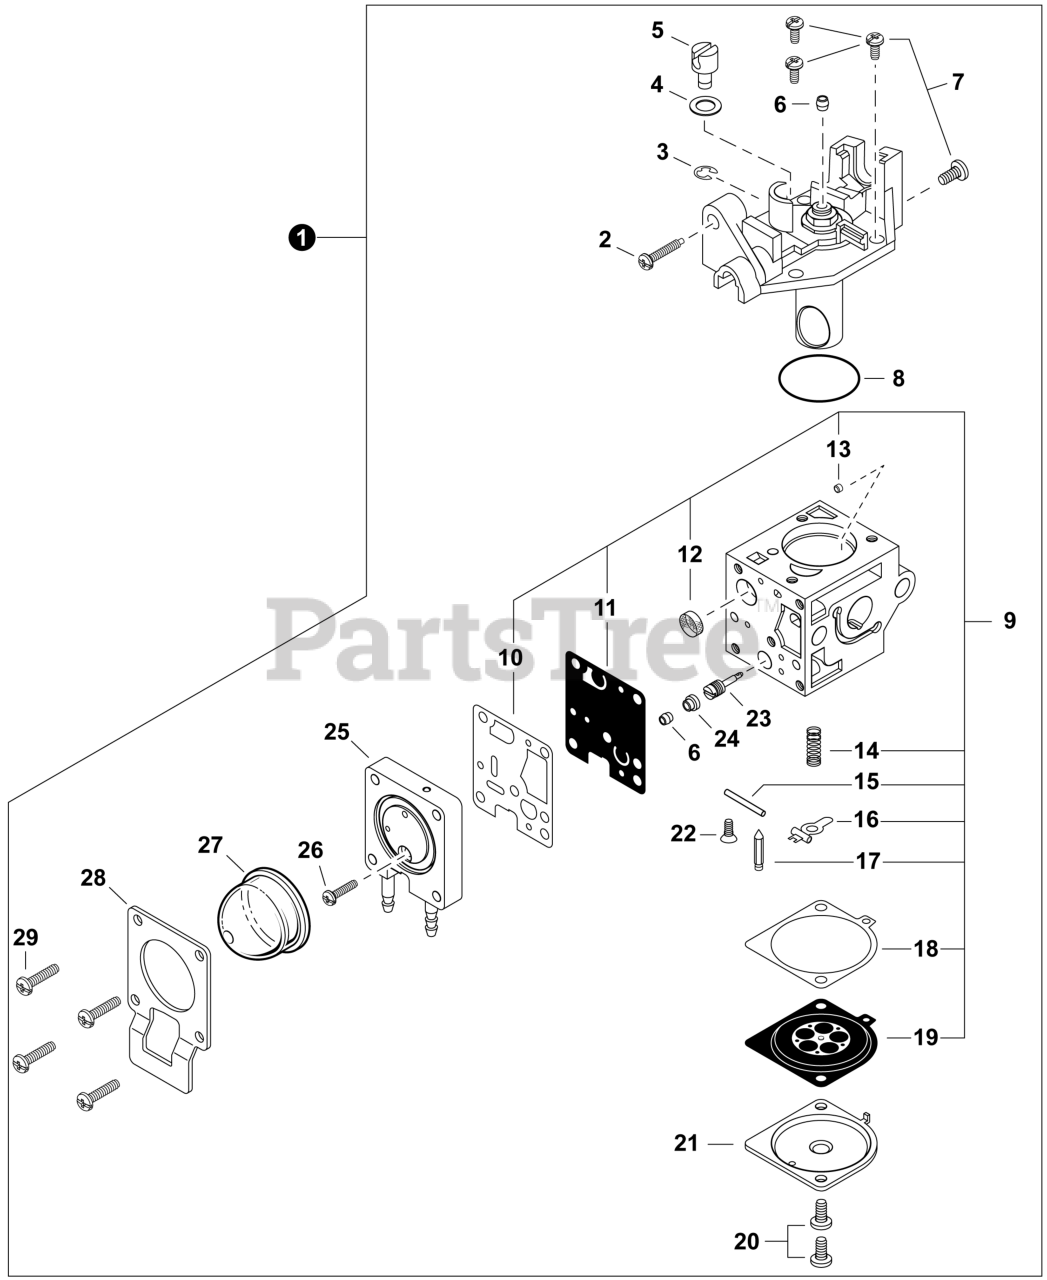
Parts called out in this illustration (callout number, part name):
1	CARBURETOR GL-4
2	SCREW, THROTTLE ADJUST
3	E-RING
4	WASHER
5	SWIVEL
6	PLUG
7	SCREW
8	O-RING
9	REPAIR KIT, CARBURETOR
10	GASKET, PUMP
11	DIAPHRAGM, PUMP
12	SCREEN, FUEL INLET
13	GUIDE, ROLLER
14	SPRING, METERING LEVER
15	PIN, METERING LEVER
16	LEVER, METERING
17	VALVE, INLET NEEDLE
18	GASKET, METERING DIAPHRAGM
19	DIAPHRAGM, METERING
20	SCREW
21	COVER, METERING DIAPHRAGM
22	SCREW
23	NEEDLE, HIGH SPEED
24	CAP, LIMITER
25	BODY ASSY, PURGE
26	SCREW M3x10
27	BULB, PURGE
28	RETAINER, PURGE BULB
29	SCREW M3x14
